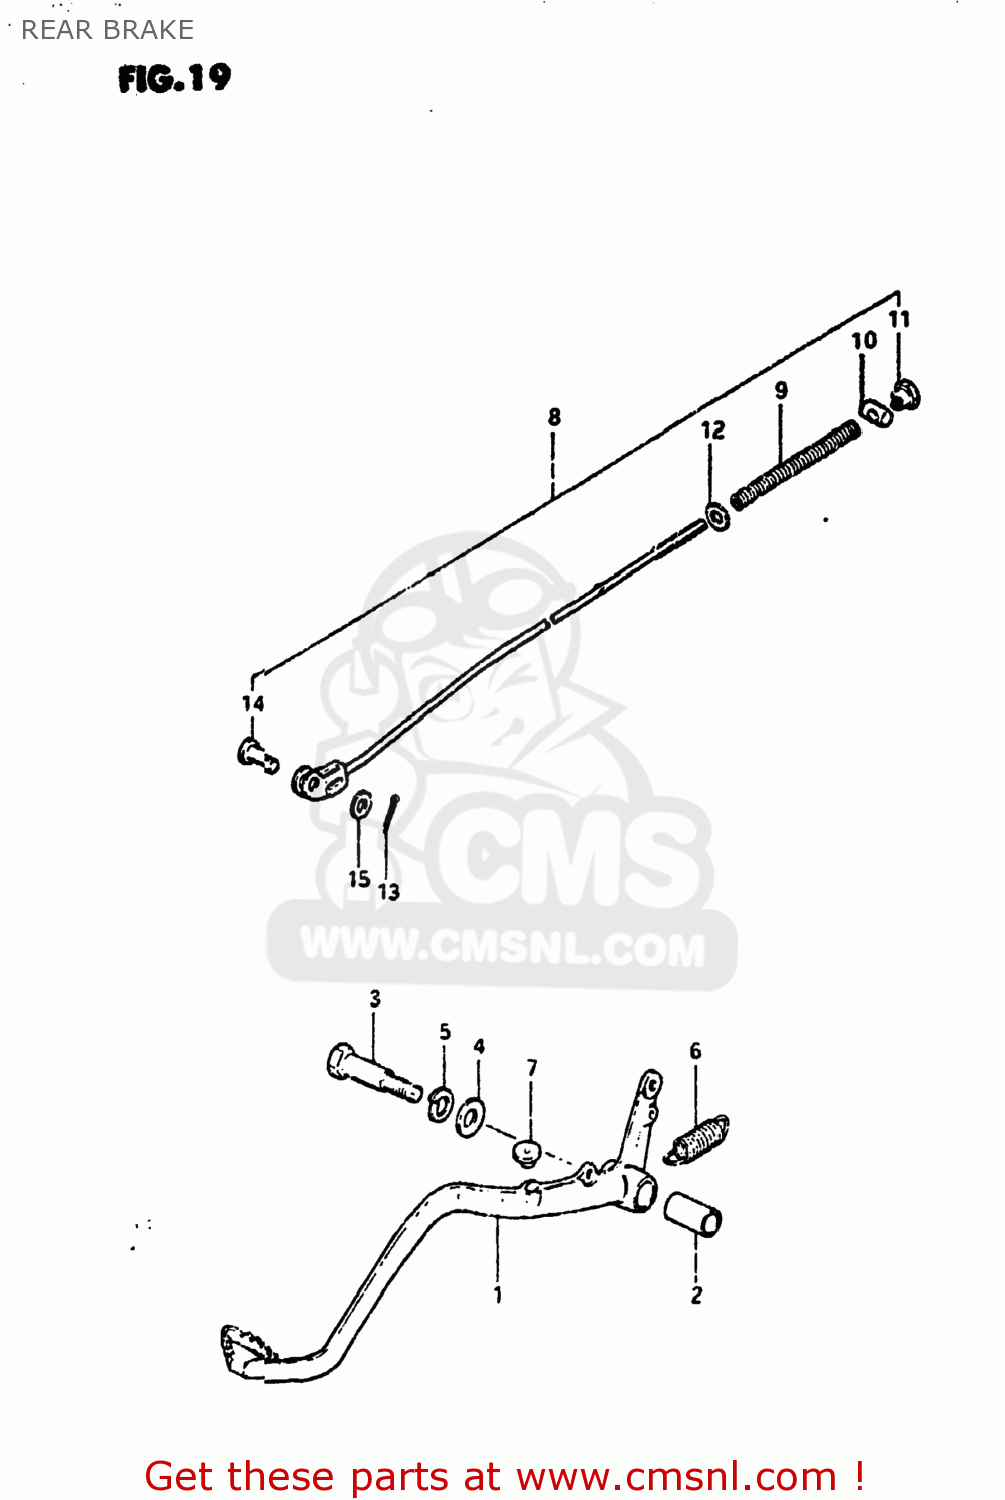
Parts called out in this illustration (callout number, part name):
1	PEDAL,BRAKE
2	SPACER(10.5X16X30)
3	BOLT
4	WASHER
5	LOCK WASHER
6	SPRING
7	STOPPER,BRAKE PEDAL
8	ROD ASSEMBLY,REAR BRAKE
9	SPRING
10	PIN(11X18)
11	NUT
12	WASHER
13	PIN 20X20
14	PIN(L:13.5)
15	WASHER
